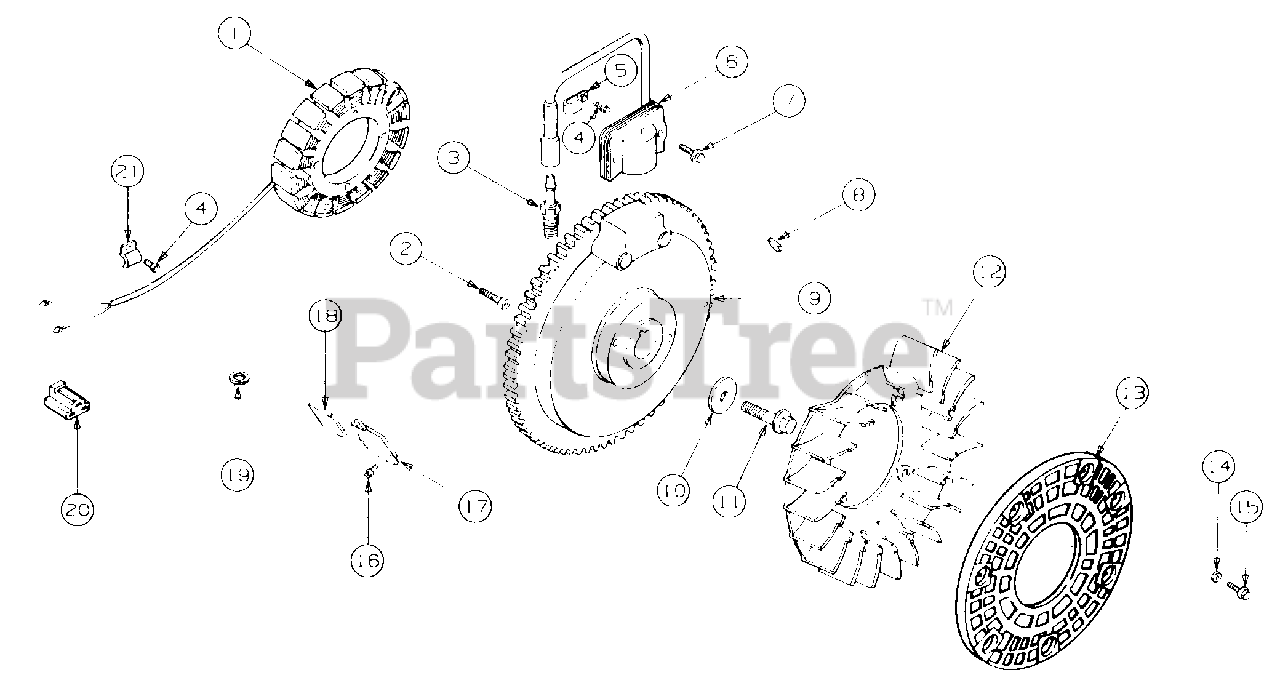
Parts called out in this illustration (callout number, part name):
1	Stator, 15 Amp
2	Screw, Stator Mounting M5 x 0.8 x 25
3	Spark Plug
4	Screw, Stator Harness Clip, M5 x 0.8 x 10
5	Clip, Cable
6	Module, Ignition
7	Screw, Ignition Module, M5 x 0.9 x 20
9	Flywheel Assy
10	Washer, Flywheel
11	Screw, Flywheel, M10 x 1.5 x 45.8
12	Fan
13	Screen, Grass
14	Spacer, Fan
15	Screw, Fan, M6 x 1.0 x 16
16	Screw, Rectifier-Regulator, M6 x 1.0 x 16
17	Rectifier-Regulator
18	Connector (3 contact)
19	Washer, Lock, 1/4
20	Connector (3 contact)
21	Clip, Stator Harness
